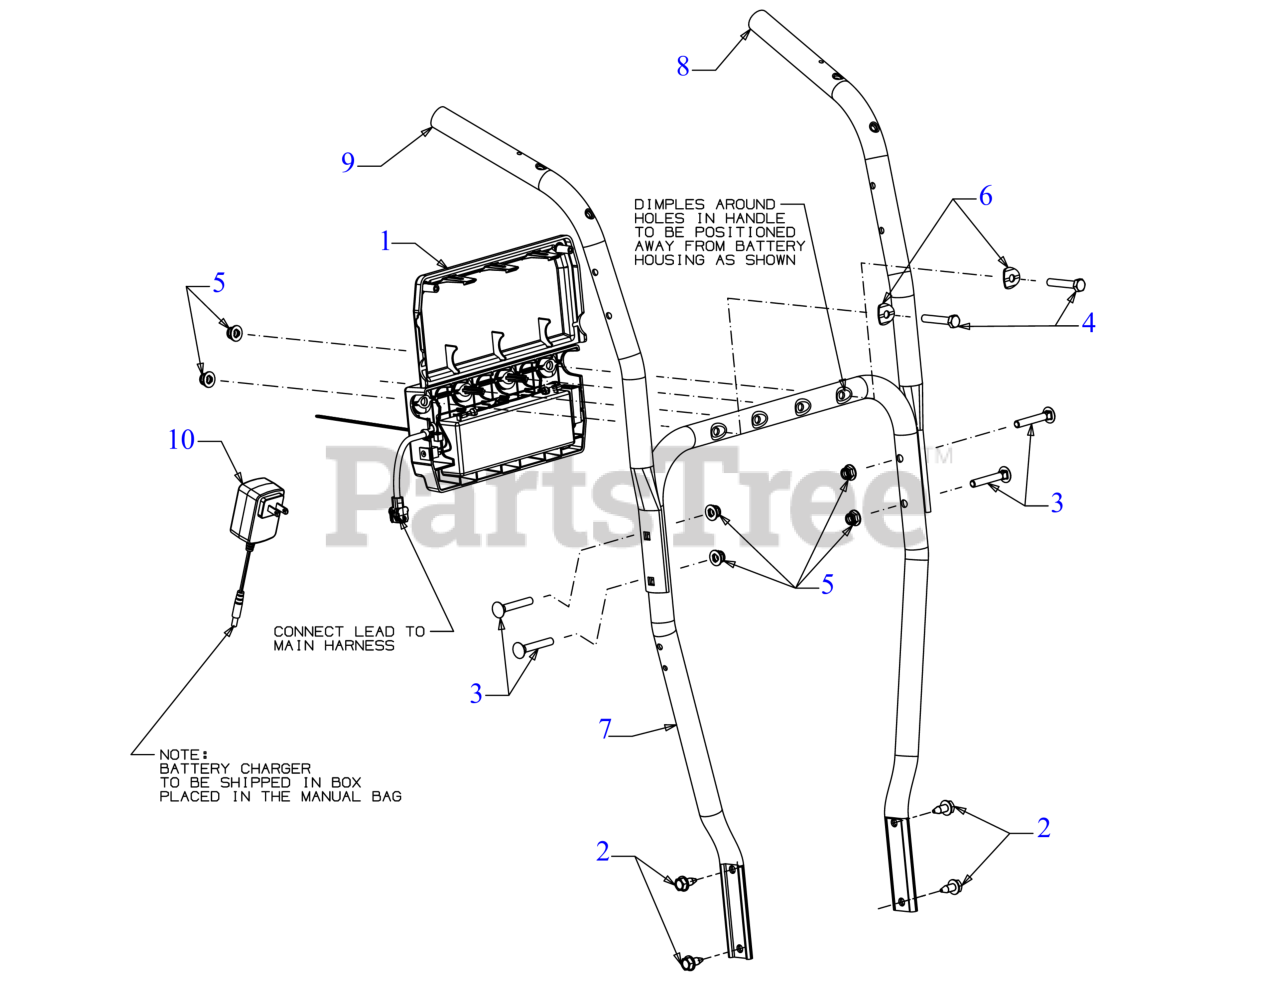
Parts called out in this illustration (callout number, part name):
1	BATTERY (12V 2.6AH)
1	7" CABLE TIE
1	EFI JUMPER HARNESS
1	BATTERY HOUSING
2	SCREW 5/16-18 x .750
3	CARRIAGE BOLT 5/16-18 x 2.00 GR5
4	SCREW 5/16-18 x 1.75 GR5
5	FLANGE LOCK NUT 5/16-18
6	SADDLE WASHER
7	LOWER HANDLE
8	UPPER HANDLE (LH)
9	UPPER HANDLE (RH)
10	BATTERY CHARGER
